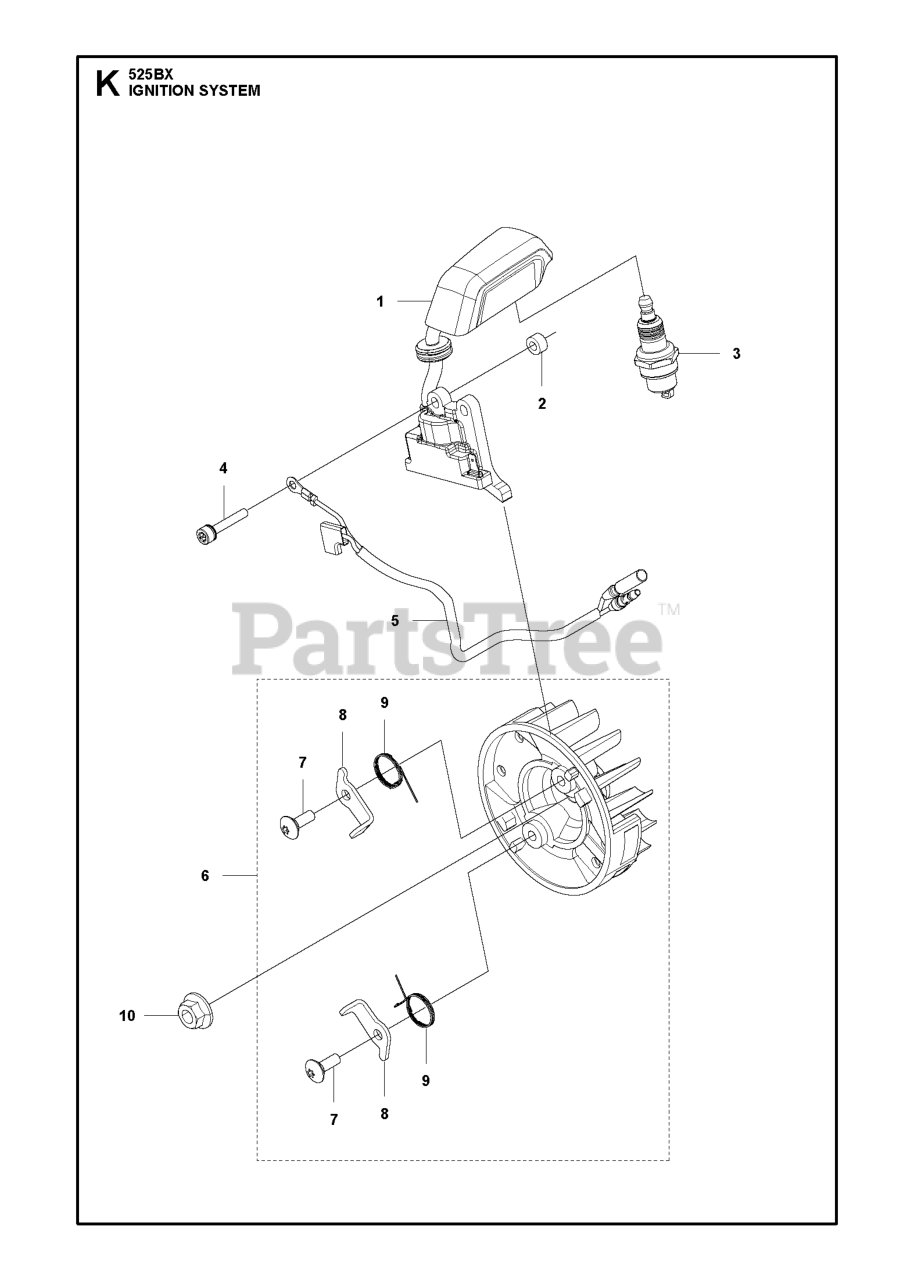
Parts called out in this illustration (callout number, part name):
1	IGNITION COIL ASSY
3	SPARK PLUG BPMR8Y
4	BOLT M4 X 25
6	FLYWHEEL ASSY
7	BOLT
8	RATCHET
9	SPRING
10	NUT
